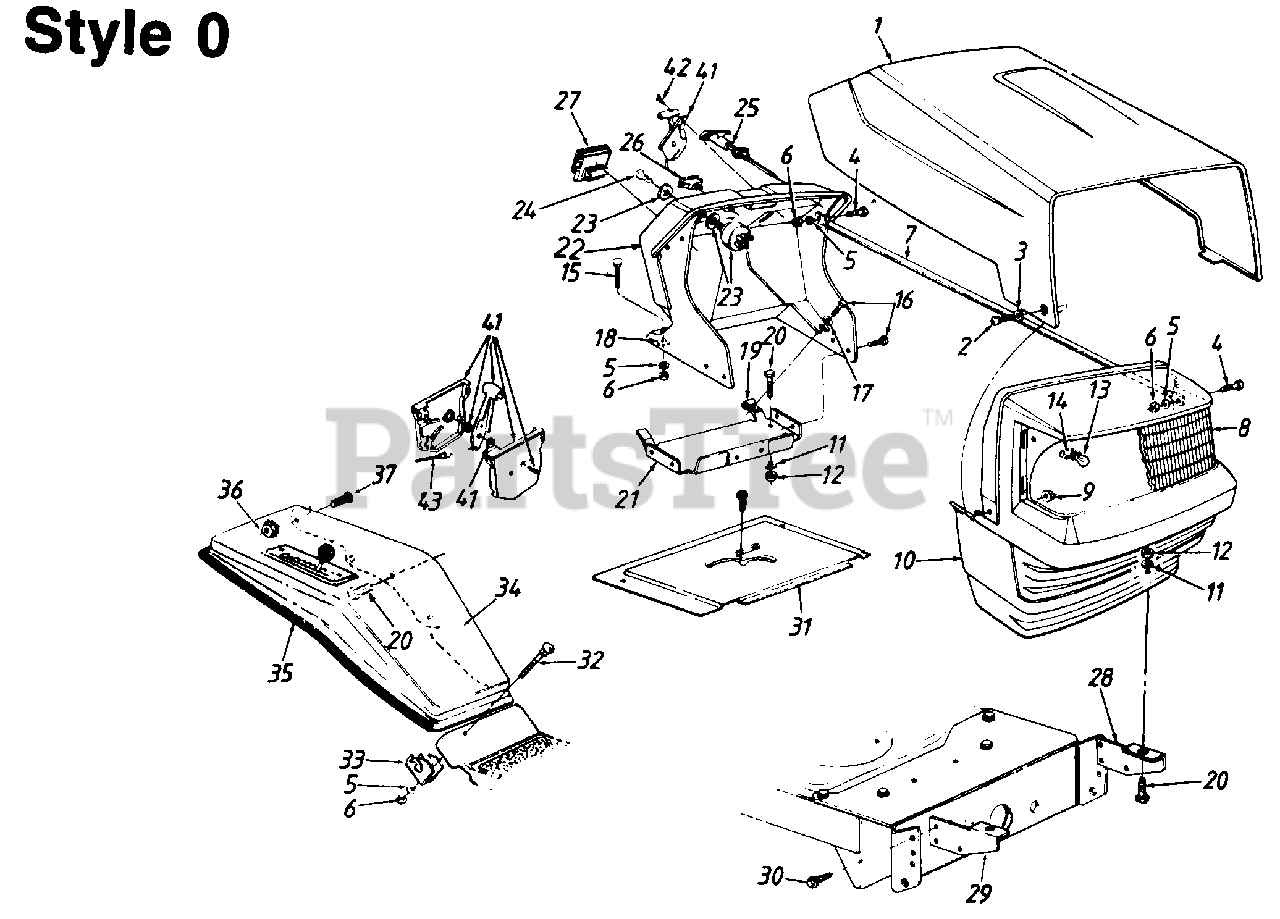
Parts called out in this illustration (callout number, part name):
1	Hood
2	Shld. Bolt .375" Dia. x .125" Lg.
3	Spr. Wash. .265" I.D. x .562" O.D.
4	Hex Bolt 1/4-20 x .62" Lg.
5	L-Wash. 1/4" I.D.
6	Hex Nut 1/4-20 Thd.
8	Headlight Lens
9	Flange L-Nut 1/4-28 Thd.
10	Grille
11	L-Wash. 5/16" I.D.
12	Hex Nut 5/16-18 Thd.
13	Lamp
14	Socket
15	Carriage Bolt 1/4-20 x 1.0" Lg.
16	Hex Wash. Hd. TT-Tap Scr. 1/4-20 x .5" Lg.
17	Fl-Wash. .281" I.D. x .73" O.D.
18	Bolt Retainer 1/4" I.D.
19	Speed Nut 1/4-20 Thd.
20	Hex Bolt 5/16-18 x .75" Lg.
21	Gas Tank Support Brkt.
23	Ignition Switch
24	Ignition Key
25	Choke Control
26	Light Switch
27	Ammeter
28	Grille Mtg. Brkt.-L.H.
31	Shift Cover
32	Carriage Bolt 1/4-20 x 2.0" Lg.
33	Fender Clamp
36	Hex Sems Nut #10-24 Thd.
37	Truss Mach. Scr. #10-24 x .5 Lg.
41	Throttle Box Ass'y.
42	Truss Mach. AB-Tap Scr. #10 x .5" Lg.
43	Throttle Control Wire
